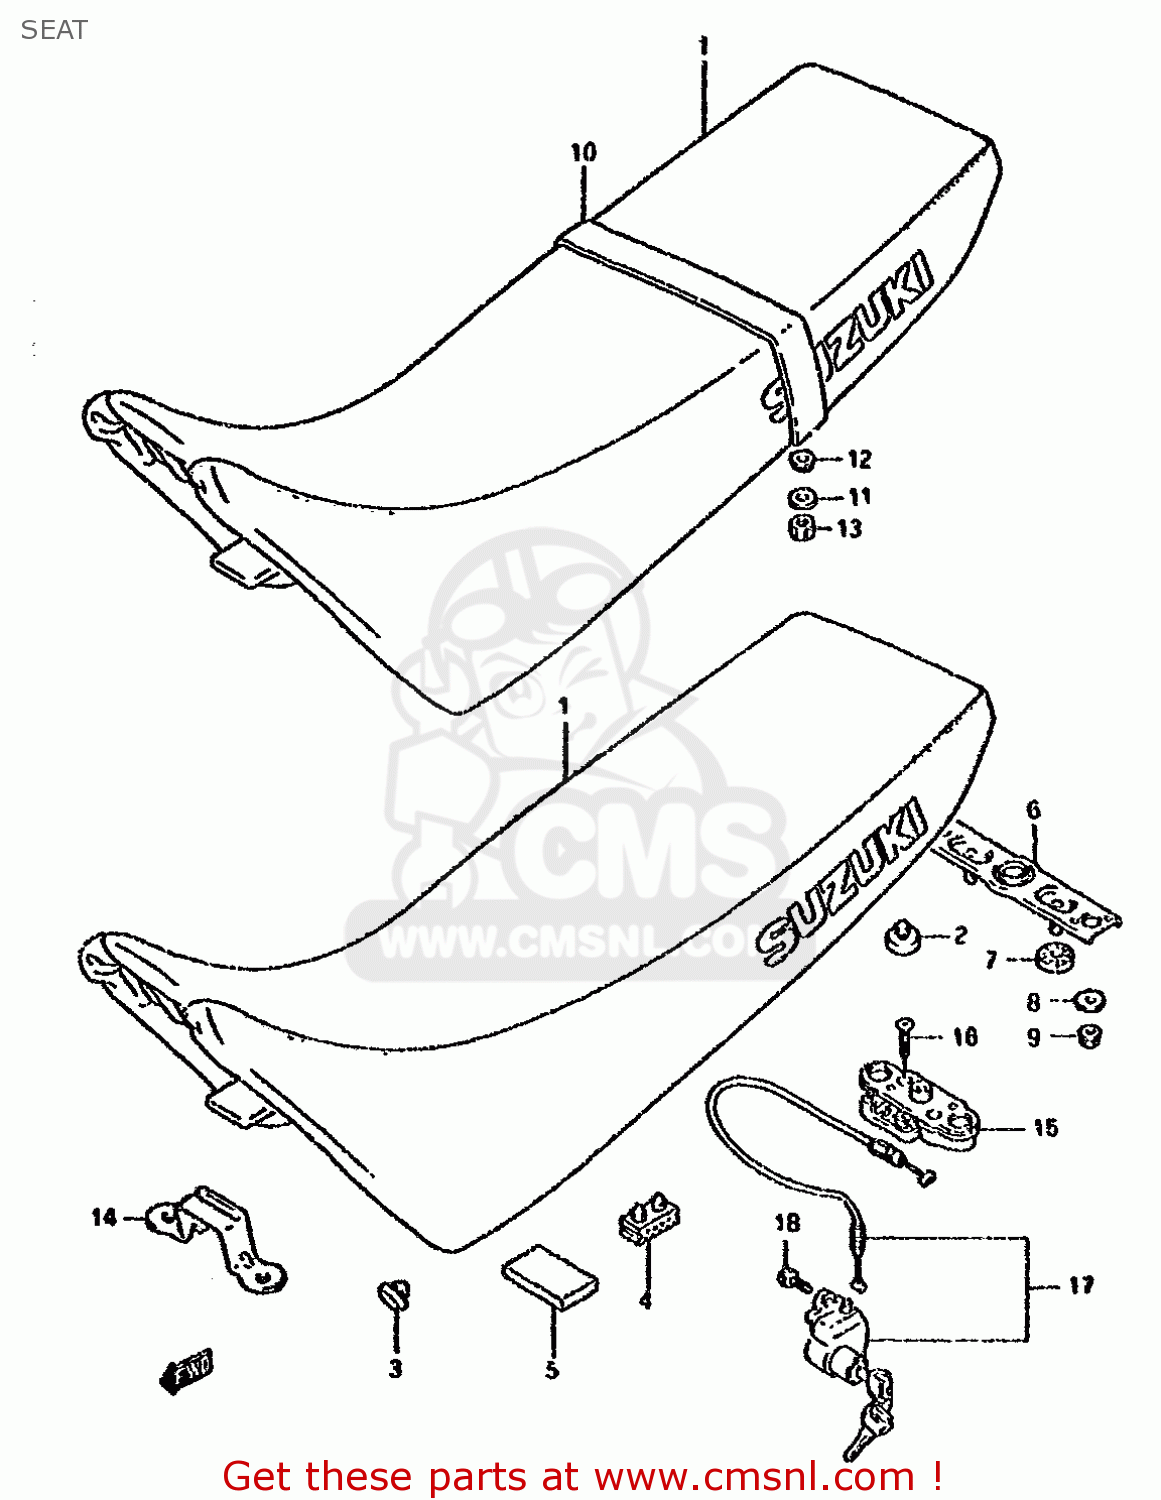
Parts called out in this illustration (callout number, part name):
1	SEAT SET
2	CUSHION
3	CUSHION
4	CUSHION,SEAT(40X20X15)
5	CUSHION,BATTERY
6	STRIKER,SEAT LOCK
7	CUSHION,SEAT LOCK(10X22X6)
8	WASHER
9	NUT
10	BAND,SEAT GRIP
11	WASHER
12	WASHER
13	NUT
14	BRACKET,SEAT FR FOOK
15	BRACKET,SEAT SUPPORT,RIGHT
16	SCREW
17	LOCK SET, SEAT
18	BOLT(6X12)
